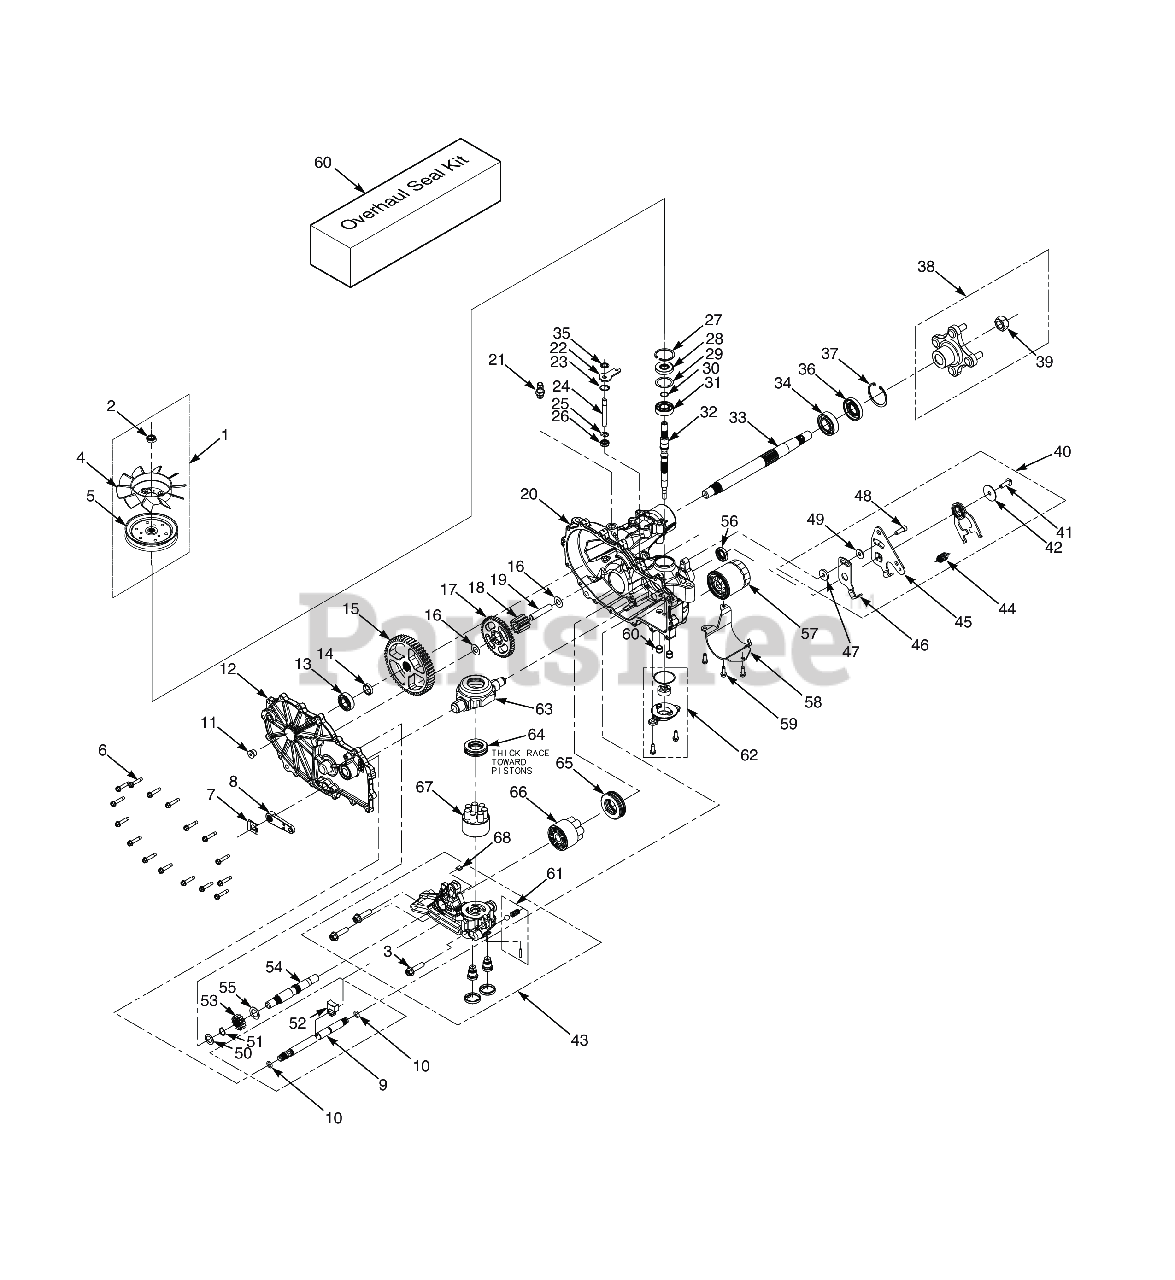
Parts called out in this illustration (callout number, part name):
1	Kit, Fan & Pulley
2	Nut, Hex Locking 1/2-20
3	Screw, Hex Flange Head 3/8-16 x 1-1/2"
4	Fan (order through Hydro-Gear)
5	Pulley, Cupped 4-1/2" Dia.
5	Hub, Pulley
6	Clip, Brake Lever (order through Hydro-Gear)
7	Clip, Retaining
8	Lever, Brake (order through Hydro-Gear)
9	Shaft, Brake
10	O-Ring, -111 x .103 x 424
11	Straight Thread Plug
12	Kit, Side Cover RH
12	Kit, Side Cover LH
13	Bearing, Ball .75 x 40 x 12
14	Spacer, .75 x 1.0 x .257
15	Gear, 54T
16	Washer, .5 x 1.0 x .03
17	Gear, 45T
18	Gear, 11T Steel
19	Jackshaft Pin
20	Kit, Housing RH
20	Kit, Housing LH
21	Fitting, Transmission
22	Arm, By-Pass
23	R i n g , Retaining .750 Internal
24	Rod, By-Pass
25	Ring, .Retaining .375 External
26	Seal, Lip .375 x .75 x .25
27	R i n g , Retaining 2.06 Internal
28	Seal, Lip 17 x 40 x 7
29	Washer, 1.23 x 1.56 x .04
30	Ring, Retaining Wire
31	Bearing, Ball 17 x 40 x 12 Open
32	Shaft, Input
33	Kit, Shaft, Axle
34	Bearing, Ball 1.0 x 52 x 15 Open
35	Ring, Retainging .375 External
36	Seal, Lip 25 x 52 x 10 TC Gray
37	R i n g , Retaining 2.06 Internal
38	Hub Kit
39	Nut, Hex Locking 3/4-16
40	Kit, RTN Bi-Directional (Left Side)
41	Bolt, Hex Head Cap Screw 5/16-24 x 1" Patch
42	Washer, .343 x 1.5 x .062
43	Kit, Center Section RH
43	Kit, Center Section LH
44	Spring, Extension, RTN - 44lbs
45	Arm, Control
46	Arm, Neutral (Right Side)
46	Arm, Neutral (Left Side)
47	Spacer, .320 x 1.005 x .179
48	Bolt, Hex Head Cap Screw 5/16-24 x 1" Patch
49	Washer, 7/16 x 7/8 OD x .06 HT
50	Washer, HT .62 ID x 1.0 OD x .05 Thick
51	Ring, Retaining .625
52	Pawl, Brake
53	Gear, 14T Steel
54	Shaft, Motor
55	Washer, .72 x 1.16 x .04
56	Seal, Lip 18 x 32 x 7
57	Filter, Oil
58	Guard, Filter (Right Side)
59	Bolt, 1/4-20 x 3/4"
60	Seal Kit
61	Kit, Charge Relief
62	Kit, Charge Pump
63	Trunnion, Swashplate
64	Ball Thrust Bearing
65	Thrust Ball Bearing Assembly
66	Kit, Motor Cylinder Block
67	Kit, Cylinder Block
68	Plate, By-Pass
69	Kit, Charge Relief
